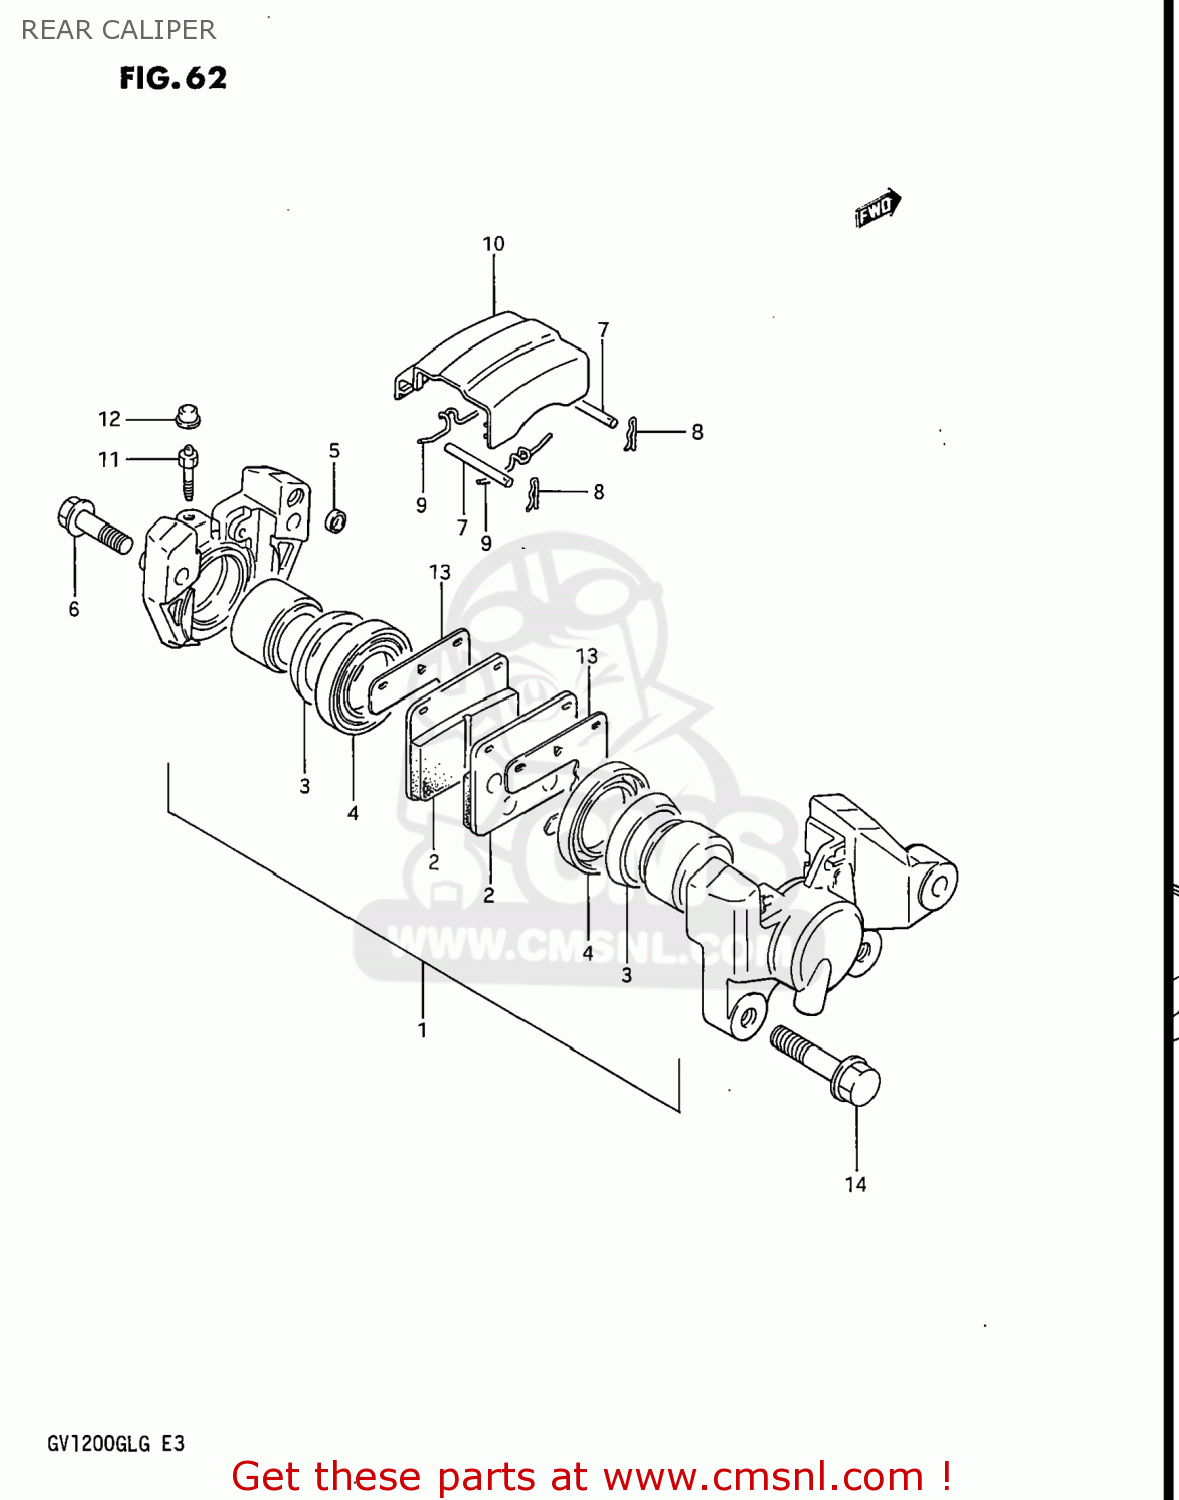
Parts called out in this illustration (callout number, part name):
1	PISTON & PAD SET
2	PAD,BRAKE
3	SEAL,PISTON
4	BOOT,PISTON
5	SEAL,JOINT
6	BOLT,HOUSING
7	PIN,PAD
8	CLIP,PAD PIN
9	SPRING
10	COVER,DUST
11	BLEEDER
12	CAP,BREATHER
13	SHIM,RR CALIPER
14	BOLT 10X30
